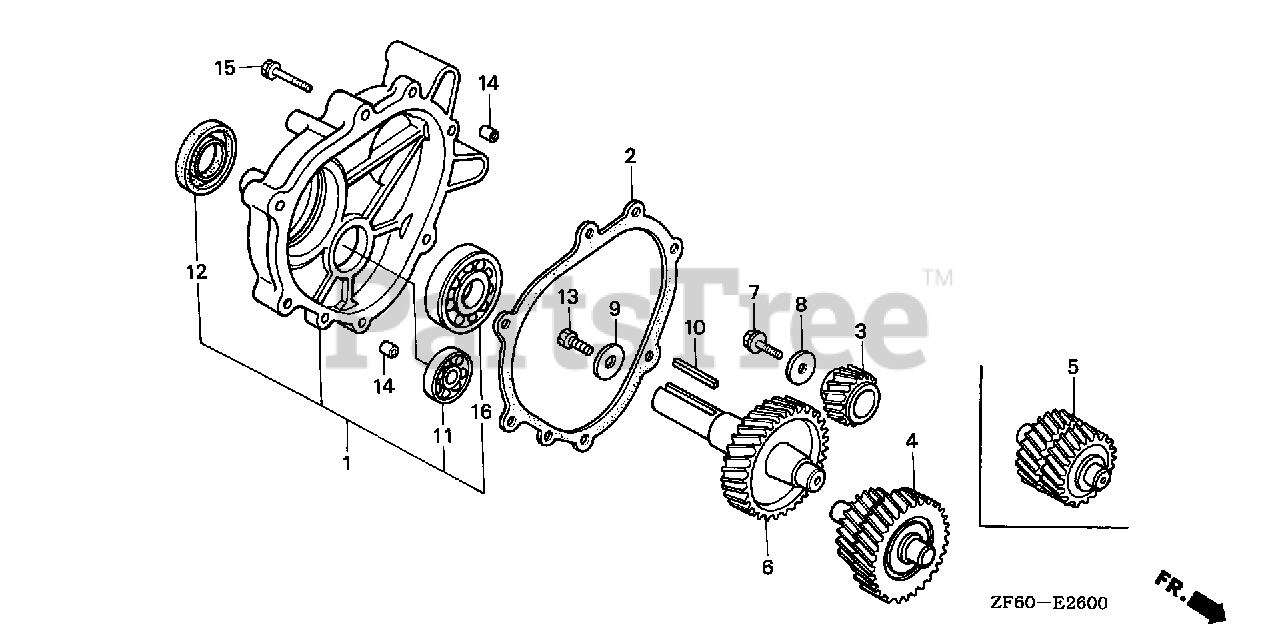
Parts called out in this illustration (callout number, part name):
1	COVER ASSY., GEAR CASE
2	GASKET, CHAIN CASE COVER
3	GEAR, PRIMARY DRIVE (22T)
4	COUNTERSHAFT (21T/27T)
6	SHAFT, P.T.O. (33T)
7	BOLT, FLANGE (8X25)
8	WASHER (8.5X42X4.5)
10	KEY (7X7X33) (OVER SIZE) (YELLOW)
11	BEARING, RADIAL BALL (6202) (NTN)
12	OIL SEAL (30X46X8)
14	PIN, DOWEL (8X14)
15	BOLT, FLANGE (8X40)
16	BEARING, RADIAL BALL (6206)
